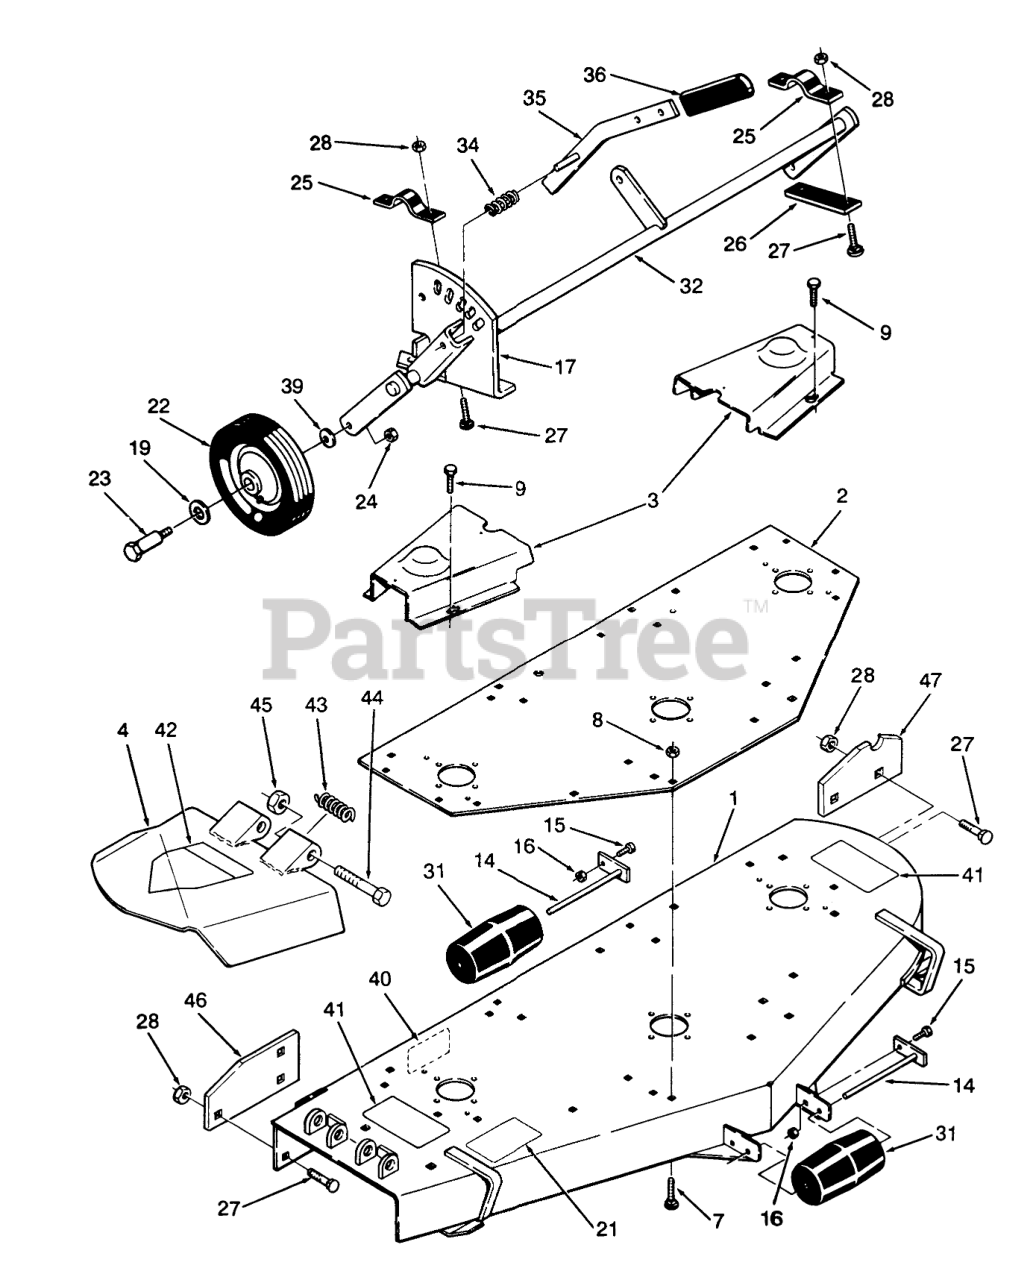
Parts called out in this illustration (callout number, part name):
1	WLDMT-60" SC DECK R
2	PLATE-TOP REINFOR R
3	Belt Cover
4	Chute Guard Assembly
7	Bolt
8	NUT
9	Bolt
14	ROLLER-SHAFT
15	Bolt
16	Nut
17	Quadrant
19	Washer
21	DECAL-BELT INSTALL
22	ASSY-GAUGE WHEEL
23	Bolt 3/8-16 x 3 1/4
24	NUT
25	Clamp
27	BOLT-CARR
28	NUT
31	ROLLER-ANTI SCALP
32	Gage Wheel Support
34	SPRING-COMPRESSION
35	Lever
39	SPACER
40	DECAL-HOC
41	DECAL-DANGER, THROWN OBJECT
42	DECAL-DANGER
43	SPRING
44	SCREW-HH
45	NUT-LOCK, NI
46	PLATE-WEAR R.H. R
47	WearPlateLH
